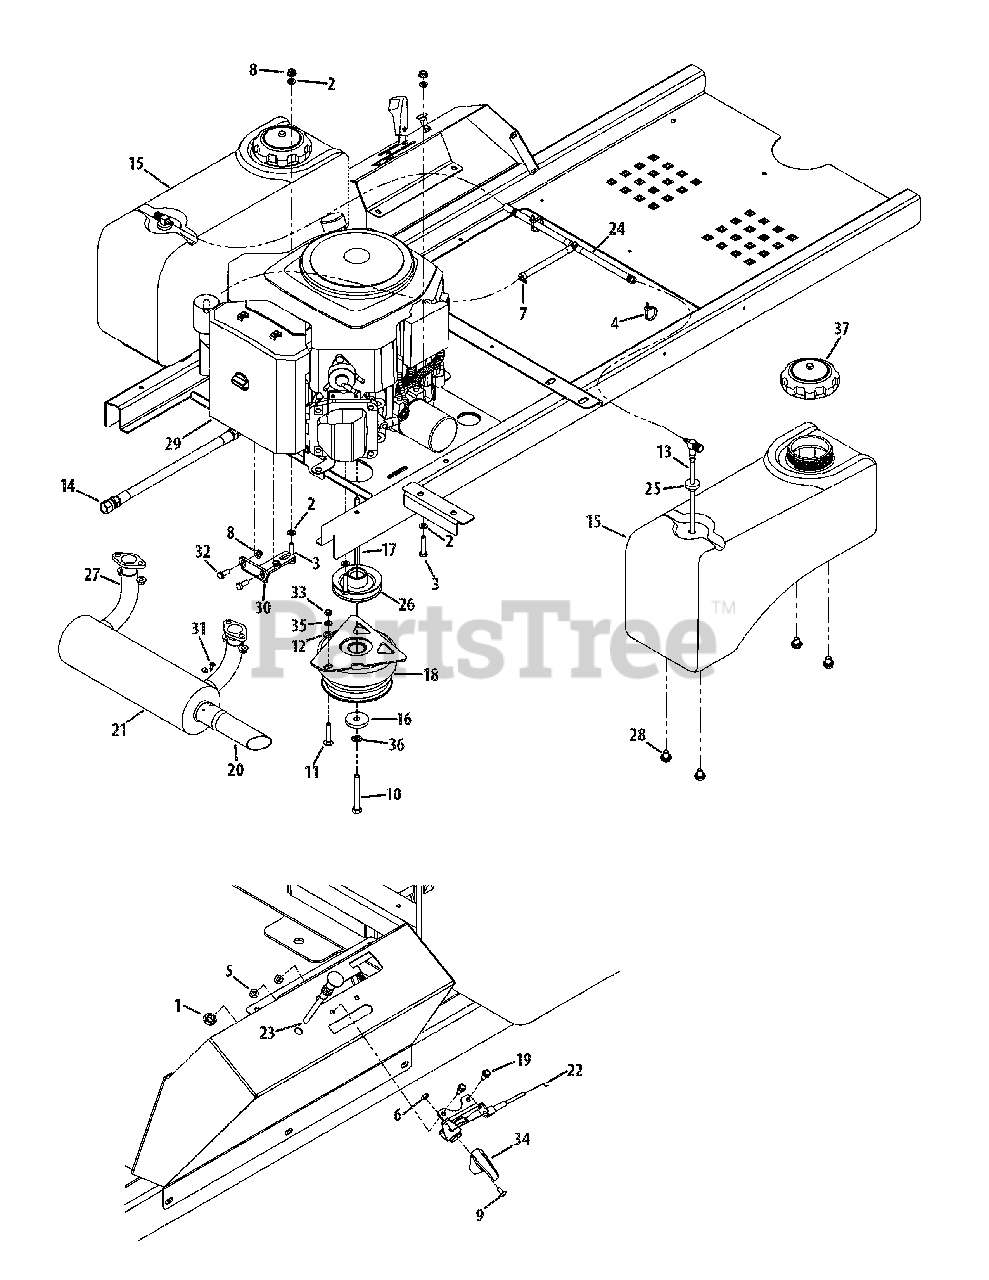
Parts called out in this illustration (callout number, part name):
1	Jam Nut, 3.8-24
2	Washer, .344 x .688 x .063
3	Hes Screw, 5.16-18 x 1.50
4	Cable Tie
5	Nylock Nut, #10-32
6	Nut, #8-32
7	Hose Clamp
8	Flange Counterlock Nut, 5.16-18
9	Machine Screw, #8-32 x .356
10	Hex Screw, 7.16-20 x 3.00
11	Carriage Bolt, 5.16-18 x 1.75
12	Washer, .406 x .750 x .063
13	Pick-Up Fuel Fitting
14	Oil Drain Hose
15	Fuel Tank
16	Washer, .438 x 1.745 x .250
17	Key, .250 x .250 x 2.75
18	Brake Clutch
19	Flange Screw, #10-32 x .500
20	Exhaust Pipe
21	Muffler
22	Throttle Control Cable
23	Choke Cable
24	Fuel Hose Assembly
25	Fuel Tank Grommet
26	Drive Pulley
27	Flange Nut, M8-1.25
28	Hex Screw, 3.8-16 x .500
29	Kohler CV670-0013 Replacement Engine
29	Kohler CV23-75592 Replacement Engine
31	Hex Washer Screw, #10-16 x 0.500
32	Hex Screw, 5.16-18 x .75
33	Jam Nut, 5.16-18
34	Throttle Control Knob
35	Lock Washer, 5.16
36	Lock Wash, 7.16
